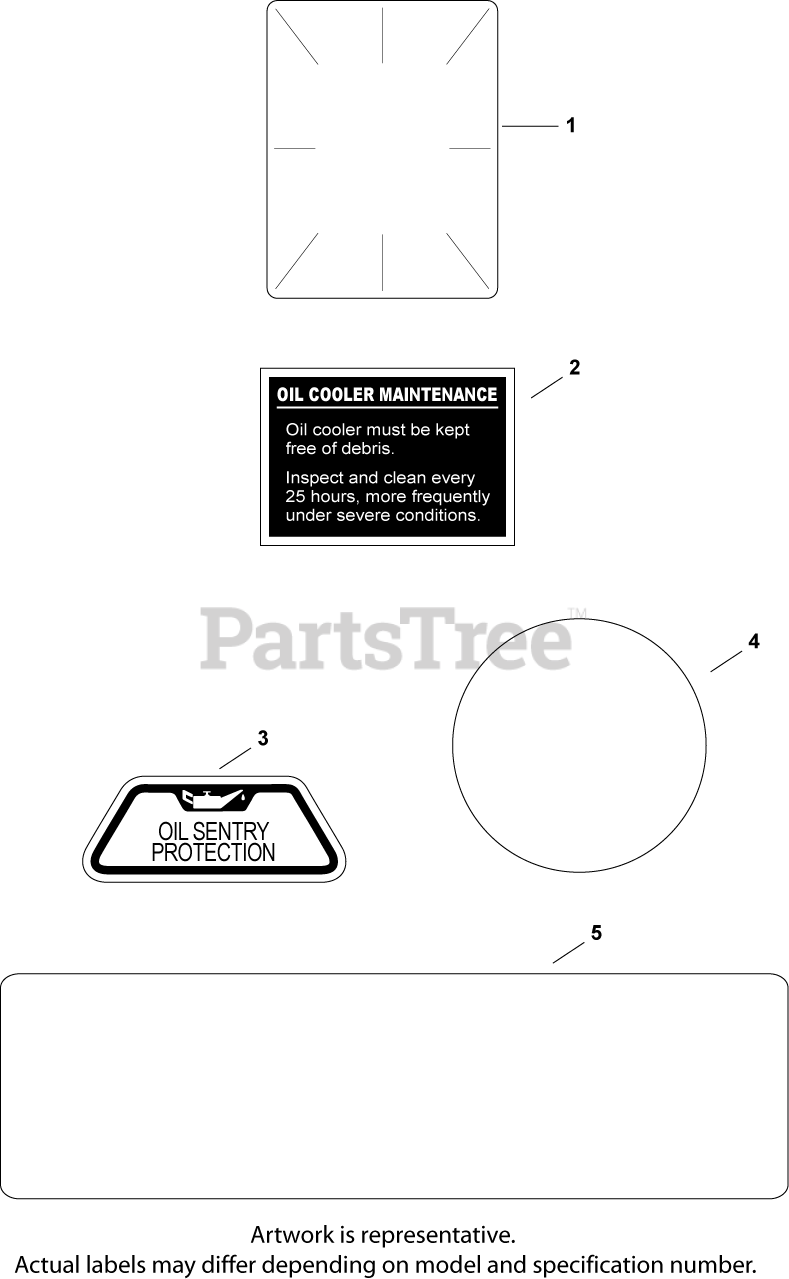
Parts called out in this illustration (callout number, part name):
1	DECAL, CLEAR LAMINATE USE 25 113 70-S
2	DECAL, OIL COOLER - (#DSC)
3	DECAL, OIL SENTRY - (#DSC)
4	LABEL, (ROUND KOHLER GOLD)-USE 24 113 18
5	DECAL, 18 HP
